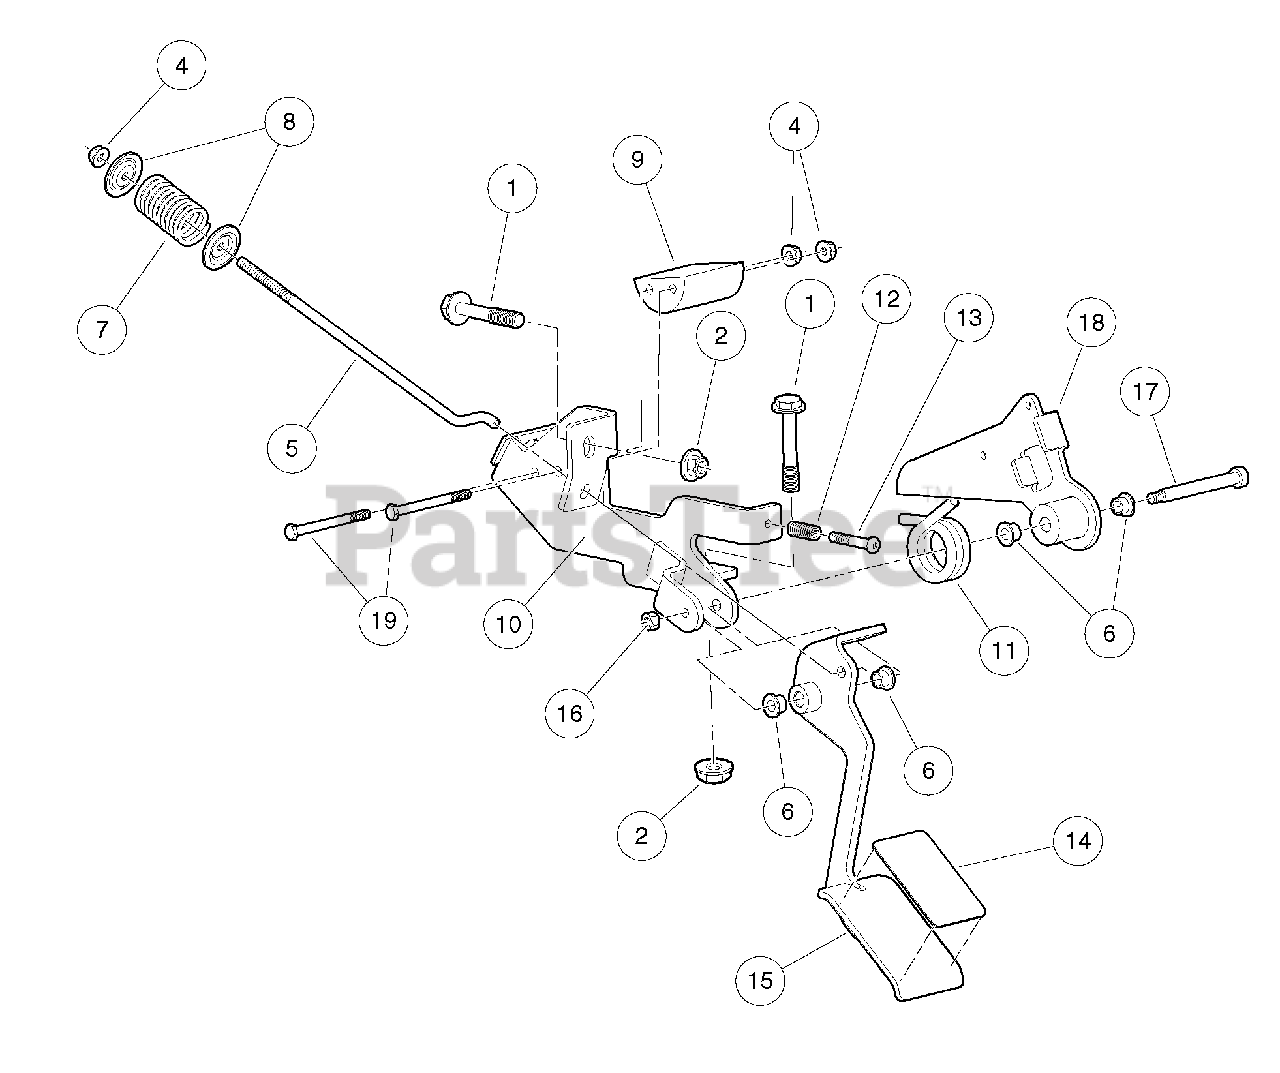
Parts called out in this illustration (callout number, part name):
1	Bolt Flanged Head, M8 X 1.25 X 65
2	Lock Nut, Flg M8 X 1.25 Nylon
3	Asm, Accelerator Pedal
4	Nut-m6x1.0 Flng All Mtl Lock
5	Pullrod, Spring, Compression
6	Bushing, Greaseless
7	Spring, Comp, Pedal, Pullrod
8	Washer, Retaining Spring, 7mm
9	Guide, Cable, Accelerator
10	Weldment, Bracket, Pedal
11	Spring, Torsion
12	Spring, Stop, Pedal
13	Bolt, Stop, Pedal
14	Pad, Grip Tape, Accelerator
15	Weldment, Pedal, Accelerator
16	Nut M6x1 Mech Def Center
17	Bolt, Shoulder, M8 X 70, Hc
18	Weldment, Lever, Lost Motion
19	Bolt, M6 X 1 X 70
